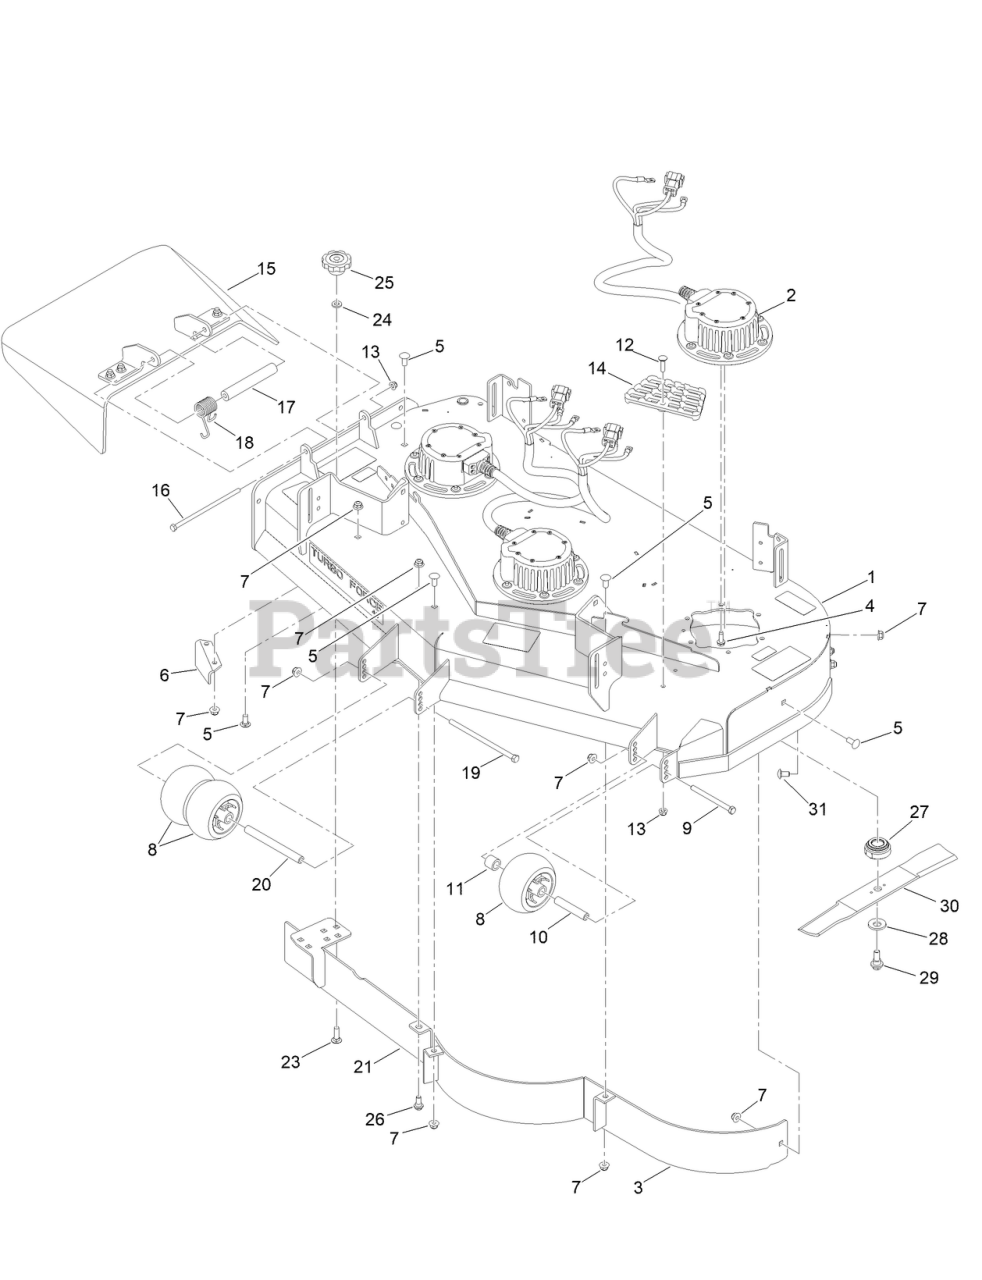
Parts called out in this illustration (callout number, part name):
1	DECK ASM-48IN
2	MOTOR/GEN-48V,
4	SCREW-THD ROLL, HWH
5	SCREW-CARR
6	BAFFLE-DISCHARGE
7	NUT-HF, NI
8	ROLLER-SCALP, ANTI
9	SCREW-HH
10	TUBE-SPANNER
11	TUBE-SPACER
12	SCREW-CARR
13	NUT-HF, NI
14	STEP-DECK
15	RUBBER DEFLECTOR ASM
16	SCREW-HH
17	SPACER
18	SPRING-TORSION
19	SCREW-HH
20	SPACER-WHEEL
23	BOLT-CARR
24	WASHER-HARDENED
26	BOLT-SHOULDER
27	RETAINER-BLADE
28	WASHER-BELLEVILLE
29	SCREW-SHOULDER,HWH
30	BLADE-16.5IN, MED SAIL
31	SCREW-CARR
